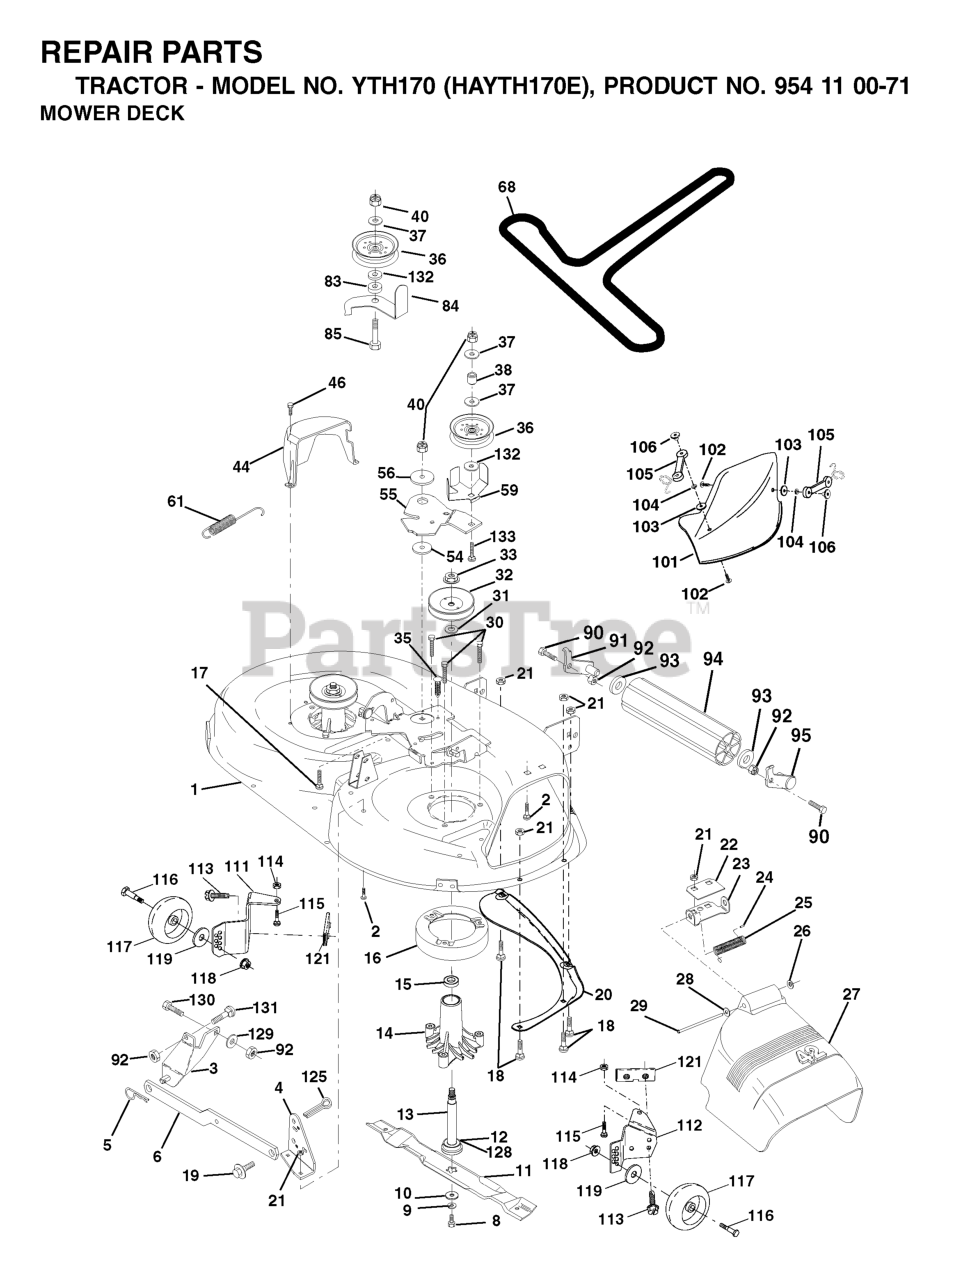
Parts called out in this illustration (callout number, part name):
1	DECK 42"
2	RP BOLT 5/16-18 X3/4 ZN/YEL GR
3	BRKT ASM SWAY BAR
4	BRKT DECK SW BAR
5	RETAINER-SPRNG RB
6	REAR SUSP ARM
8	BLADE BOLT
9	LOCKWASHER
10	WASHER.BLADE
11	BLADE.42".MULCH
12	BEARING.BALL.#6204.(MANDREL)
13	SHAFT ASM VENT
14	HOUSING.MANDREL.VENTED (MACHD)
16	STRIPPER
17	BOLT CARRIAGE
18	BOLT
19	BOLT SHD 5/16-18
20	BAFFLE.VORTEX
21	LOCKNUT
22	STIFFENER BRACKET
23	DEFLECTOR BRACKET
24	CAP-SLEEVE LT
25	SPRING TORSION
26	NUT PUSH M
27	SHIELD DEFLECTOR
28	Washer 11/32 x 5/8 x 16 Ga SD
29	ROD.HINGE
30	SCREW THDROL ROLLING WASHER HD
31	WASHER
32	PULLEY/MANDREL
33	NUT
35	FASTENER.XMAS.TREE
36	FLAT IDLER PULLEY
37	WASHER
38	IDLER SPRING SPACER
44	GUARD MANDREL LH BLACK
46	SCREW.1/4-20X5/8
54	HARDENED WASHER
55	IDLER ARM
56	SPACER.RETAINER.MOWER
59	GUARD, BELT
61	SPRING EXTENSION
68	V-BELT TRIPATH
84	KEEPER.BELT.IDLER
90	BOLT
91	BRACKET LH (A)
92	NUT
93	Washer 1 17/32 X 7/8 X 16 Ga
94	NOSE ROLLER
95	BRACKET RH (B)
101	COVER MULCH 42"
102	SCREW
104	LOCKWASHER #10
105	LATCH ASSY
106	WELDNUT
111	BRACKET WHEEL GAUGE LH 42" DK
112	BRACKET WHEEL GAUGE RH 42" DK
113	Screw Tapping 5/16-18 Unc
114	NUT
115	BOLT.CARR.5/16-18X1/2
116	BOLT, SHOULDER
117	WHEEL GAGE DONUT
118	LOCKNUT
119	WASHER.5/16.FLAT.STE.STD.
121	BRACKET.EXTRUDED.GAGE.WHEEL
125	Pin Cotter 1/4 x 1 Plated
128	WASHER FELT
129	WASHER
131	BOLT D
132	Washer 13/32 x 1-3/8 x 13 Ga.
